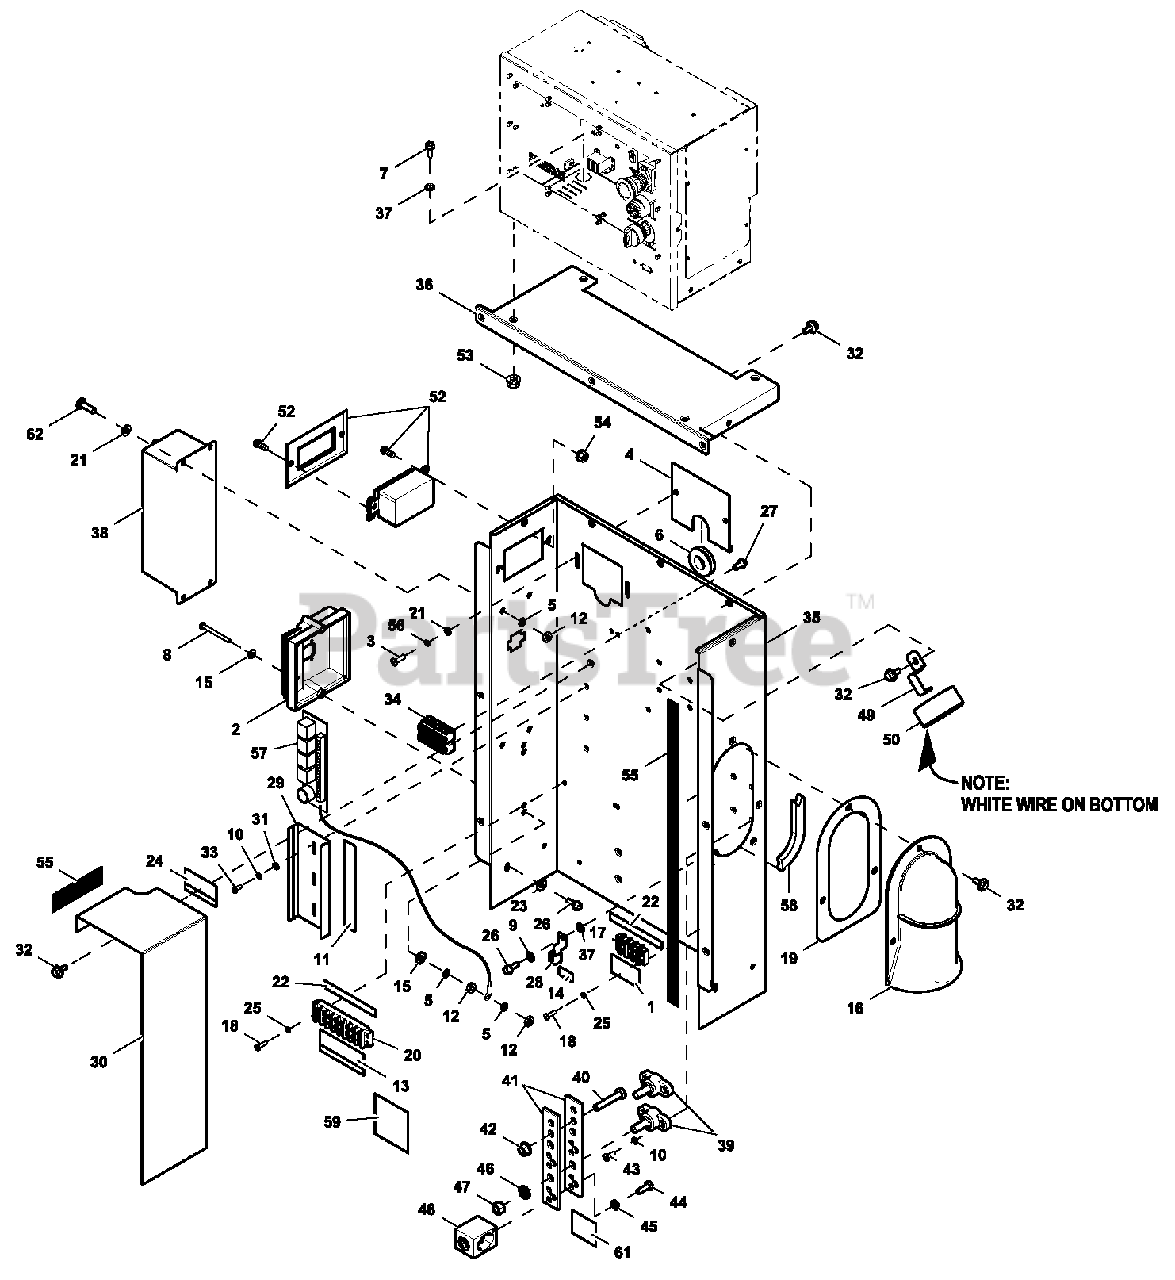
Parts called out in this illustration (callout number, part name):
1	DECAL CHARGER POWER 120VAC C2
2	ASSY PCB 2 4L IGN MOD PRGMMED
3	SCREW PHTT M5-0.8X16ZP
4	PLATE WIRE SNGL GALV
5	WASHER LOCK #10
6	GROMMET 1.25 X .25 X 1.00
7	SCREW HWHTF M6-1.0 X 16
8	SCREW PPHM #10-32X2
9	WASHER LOCK M6-1/4
10	WASHER LOCK #8-M4
11	DECAL, CONTACT RAT 30VAC/30VDC
12	NUT HEX #10-32 STEEL
13	DECAL CPL CUST CONN H CONTROL
14	DECAL GROUND LUG
15	WASHER FLAT #10 ZINC
16	COVER WIRE ENTRY CONNBOX
17	BLOCK TERM 2 0A 6X 3 X 1 1 0 0 V
18	SCREW PHTT #6-32 X 1/2 ZYC
19	GASKET WIRE ENTRY COVER
20	BLOCK TERM 2 0A 8X 6 X 1 1 0 0 V
21	WASHER FLAT M5
22	DECAL, CUSTOMER WIRE #14
23	WASHER FLAT 1/4-M6 ZINC
24	DECAL CONBOX TB2 CONNECTIONS
25	WASHER LOCK #6
26	SCREW HHTT M6-1.0X 1 6 ZYC
27	SCREW HHSP #10 X 3/8 HI-LOW
28	LUG SLDLSS #2-#8 X 17/64 CU
29	RAIL SNAPTRACK PCB HOLDER BULK (6"LG)
30	SHIELD HIGH/LOW C2 CPL H
31	WASHER FLAT M4
32	SCREW HWHT M6-1 X 16 N WA Z/JS
33	SCREW PHTT M4-0.7 X 10 ZP
34	TERM BLOCK 4PUL12-20AWG
35	BK PNL CONBOX SUPPORT C2 QTA
36	BACK PNL CONBOX TOP C2
37	WASHER LOCK EXT 1/4 STL
38	INTERFACE 1PH 120/240V
39	INTERFACE 3PH 208/240V
40	INTERFACE 3PH 416/480V
41	JUNCTION BLOCK 3/8-16
42	SCREW HHC M8-1.25X 45 C8.8
43	BUSBAR NEUTRAL BLOCK 390
44	NUT HEX FL WHIZ M8-1.25
45	SCREW PHTT M4-0.7 X 12 ZP
46	SCREW HHC 1/4-28 X 3/4 G5
47	WASHER LOCK 1/4-M6 SS
48	WASHER LOCK 3/8
49	NUT HEX 3/8-16 STEEL
50	LUG SLDLSS 600/250-1/0X1/4-28
52	OUTLET 20A GFCI125V
53	NUT FLANGE M6-1.0 NYLOK
54	NUT LOCK HEX #6-32 NYL INSERT
55	TAPE ELEC 1/2 FOAM (61" LG)
56	WASHER LOCK M5
57	ASSY RELAY PCB 12VDC
58	TRIM VINYL BLACK 1/8GP (13" LG)
59	DECAL CAUTION ELEC SHOCK SM
61	DECAL NEUTRAL
62	SCREW PPHM #10-32 X 1/2
